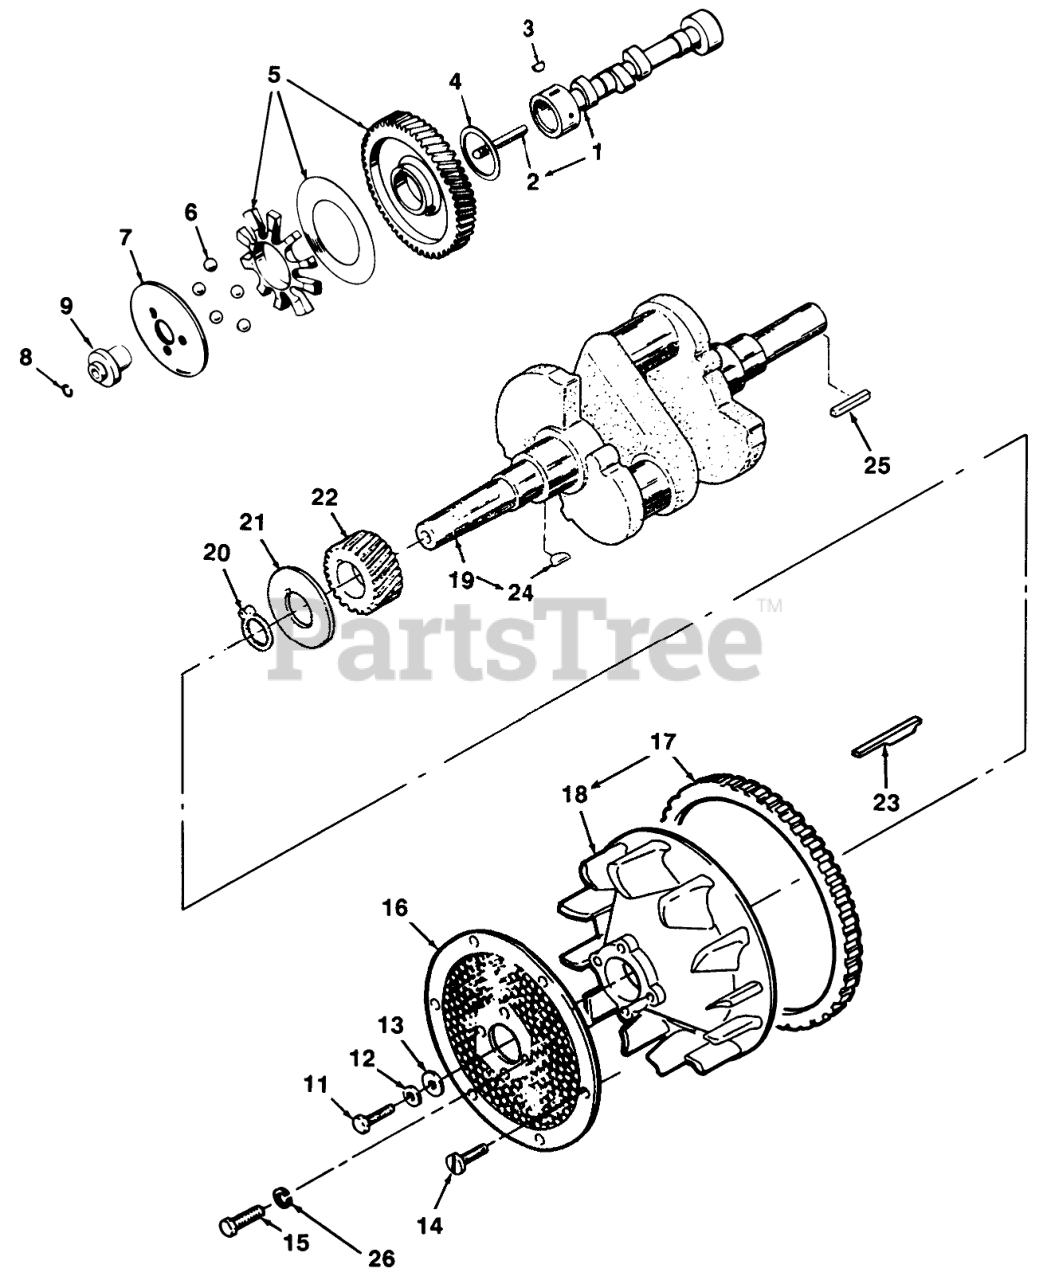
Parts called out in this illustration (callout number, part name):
1	Camshaft (Includes Center Pin)
2	PIN-CENTER
4	WASHER-THRUST
5	Camshaft Gear (Includes Plate and Spacer)
6	BEARING
7	CUP-GOVERNOR
9	HUB-GOVERNOR CUP
11	SCREW
12	WASHER-FLAT
13	WASHER-FLAT
14	Bolt
15	HX HD LOCK CAPSCREW
16	AIR INLET SCREEN
17	Ring Gear
18	Flywheel (Includes Ring Gear)
19	Crankshaft (Includes Keys)
21	WASHER
23	KEY-FLYWHEEL
25	Key
26	WASHER - LOCK (5/16")
